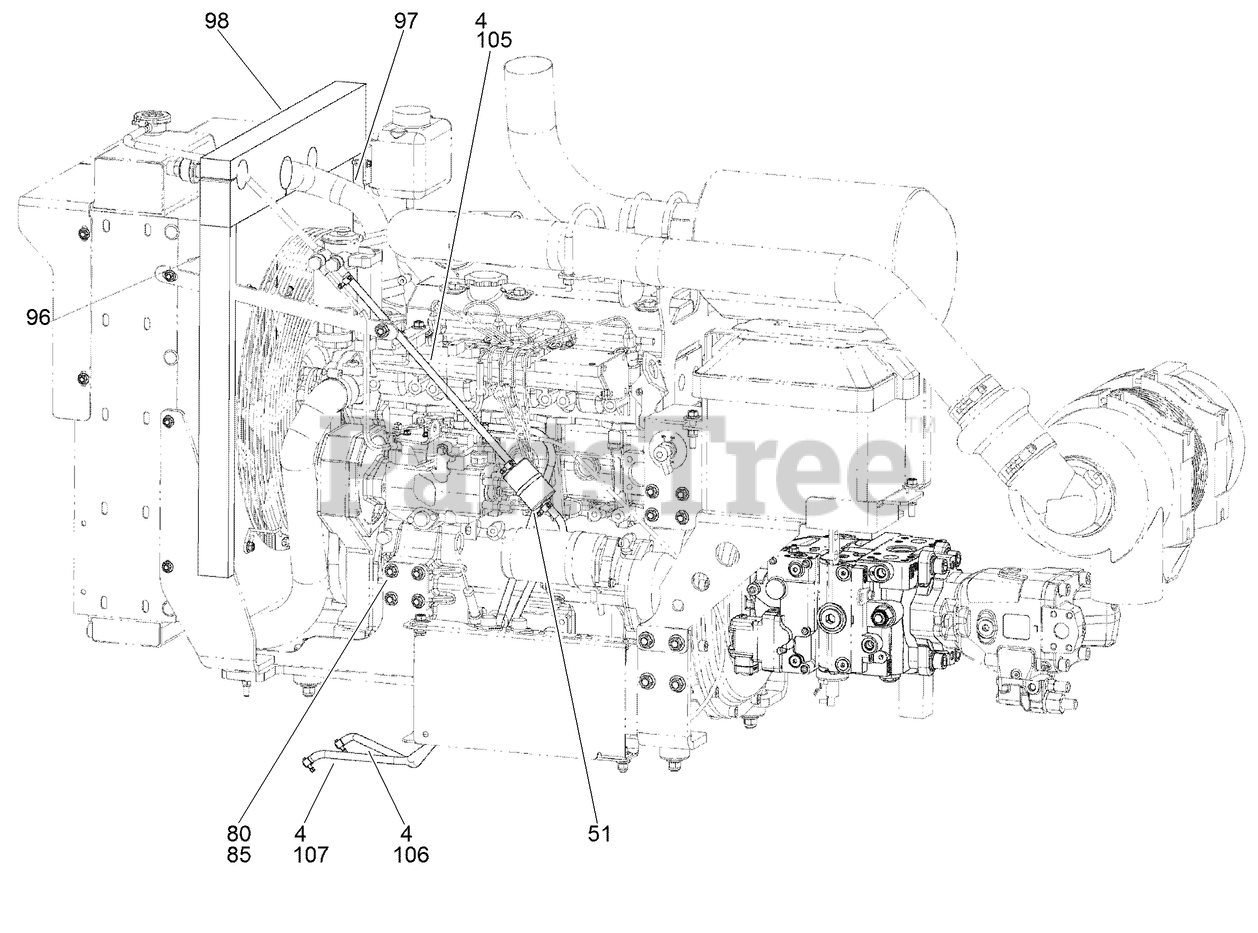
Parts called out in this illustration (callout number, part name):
4	CLAMP - Hose Type M # 06
51	FILTER-INLINE FUEL
80	NUT-FLANGE, NYLOCK
85	SCREW-FLANGE
96	FOAM SEAL
97	FOAM SEAL
98	FOAM SEAL
105	FUEL LINE - 3/8 ID, 16 Length
106	FUEL LINE - 3/8 ID, 42 Length
107	FUEL LINE - Return, 3/8 ID, 40 Length
